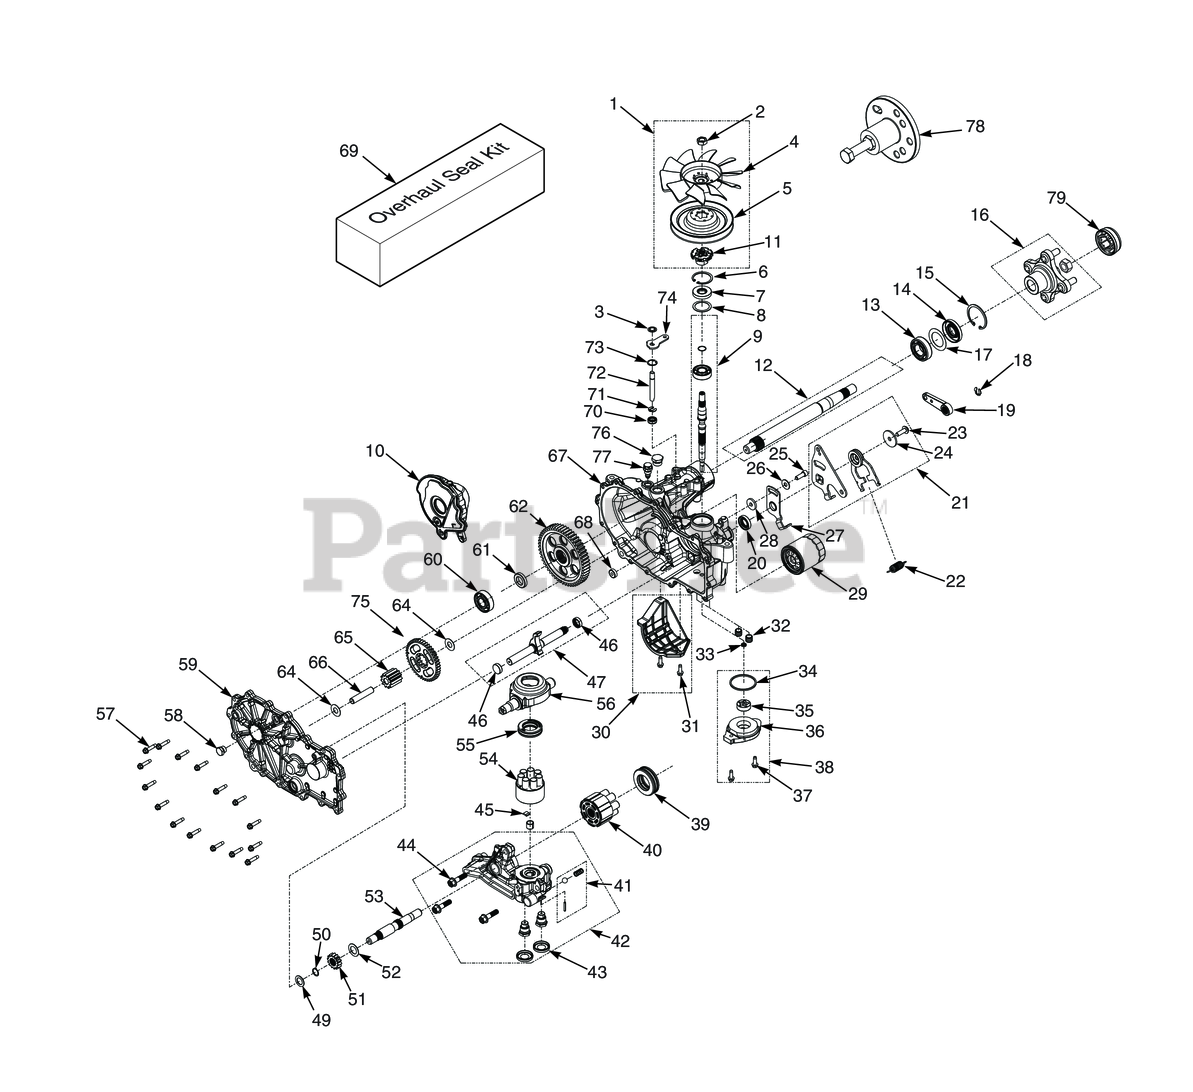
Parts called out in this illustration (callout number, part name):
1	Kit, Fan & Pulley
2	Fan Nut (order through Hydro-Gear)
3	Ring, Retainging .375 External
4	Fan, 7" (10 Blade)
5	Pulley"
6	R i n g , Retaining 2.06 Internal
7	Seal, Lip 17 x 40 x 7
8	Washer, 1.23 x 1.56 x .04
9	Kit, Input Shaft
10	Expansion Tank, Internal RH
10	Expansion Tank, Internal LH
11	Spring, Block
12	Shaft, Axle
13	Bearing, Ball 1.0 x 52 x 15 Open
14	Seal, Lip TC4 1.0 x 2.06 x .38
15	R i n g , Retaining 2.06 Internal
16	Hub, 4-Bolt
17	Washer, 1.355 x 2.035 x .021 Flat
18	Ring, Retaining External .375"
19	Handle, Brake
20	Seal, Lip 18 x 32 x 7
21	Kit, RTN Bi-Directional (Left Side)
21	Kit, RTN Bi-Directional (Right Side)
22	Spring, Extension
23	Bolt, Hex Head Cap Screw 5/16-24 x 1" Patch
24	Washer, .343 x 1.5 x .062
25	Bolt, Hex Head Cap Screw 5/16-24 x 1" Patch
26	Washer, 7/16 x 7/8 OD x .06 HT
27	Arm, Neutral (Right Side)
27	Arm, Neutral (Left Side)
28	Spacer, .32 ID x 1.005 OD x .1495 Thk
29	Filter, Oil
30	Kit, Filter Guard (RH)
30	Kit, Filter Guard (LH)
31	Screw, Hex Flange 1/4-20 x .625
32	Tibe, Connecting
33	Kit, Gerotor Seal
34	Tube, Charge Triple O-ring
35	Gerotor Assembly (1.9 cc)
36	Cover, Charge Pump
37	Screw, Hex Flange 1/4-20 x .625
38	Kit, Charge Pump
39	Thrust Ball Bearing Assembly
40	Kit, 16cc Cylinder Block Assembly (steam
41	Kit, Charge Relief
42	Kit, Center Section (Right Side)
42	Kit, Center Section (Left Side)
43	Seal, Plug 1.250 x .250
44	Screw, Hex Flange Head 3/8-16 x 1-1/2"
45	Plate, By-Pass
46	O-Ring, -111 x .103 x 424
47	Kit, Outboard, RH Rot B / LH Rot A (LH)
47	Kit, Outboard, RH Rot A / LH Rot B (RH)
48	Pawl, Brake
49	Washer, HT .62 ID x 1.0 OD x .05 Thick
50	Ring, Retaining .625
51	Gear, 14T Steel
52	Washer, .72 x 1.16 x .04
53	Shaft, Motor
54	Assembly, Block 7 Piston
55	Bearing, Thrust
56	Trunnion, Swashplate
57	Bolt, Hex Head 1/4-20 x 1-1/8"
58	Plug, External Hex Vent 9/16-18
59	Kit, Cover (Right Side)
59	Kit, Cover (Left Side)
60	Kit, Bearing
61	Spacer, .750 x 1.320 x .257
62	Gear, 54T
63	Gear, 45T
64	Washer, .5 x 1.0 x .03
65	Gear, 11T Steel
66	Jackshaft Pin
67	Kit, Housing Main (Right Side)
67	Kit, Housing Main (Left Side)
68	Magnet, Ring
69	Seal Kit
70	Seal, Lip, .375 x .75 x .25
71	Ring, .Retaining .375 External
72	Rod, By-Pass
73	R i n g , Retaining .750 Internal
74	Arm, By-Pass
75	Gear, 45T
76	Plug, 3/4-16
77	Fitting 9 /16 - 18, Breather
78	Kit, Hub Puller
79	Cap, Axle
